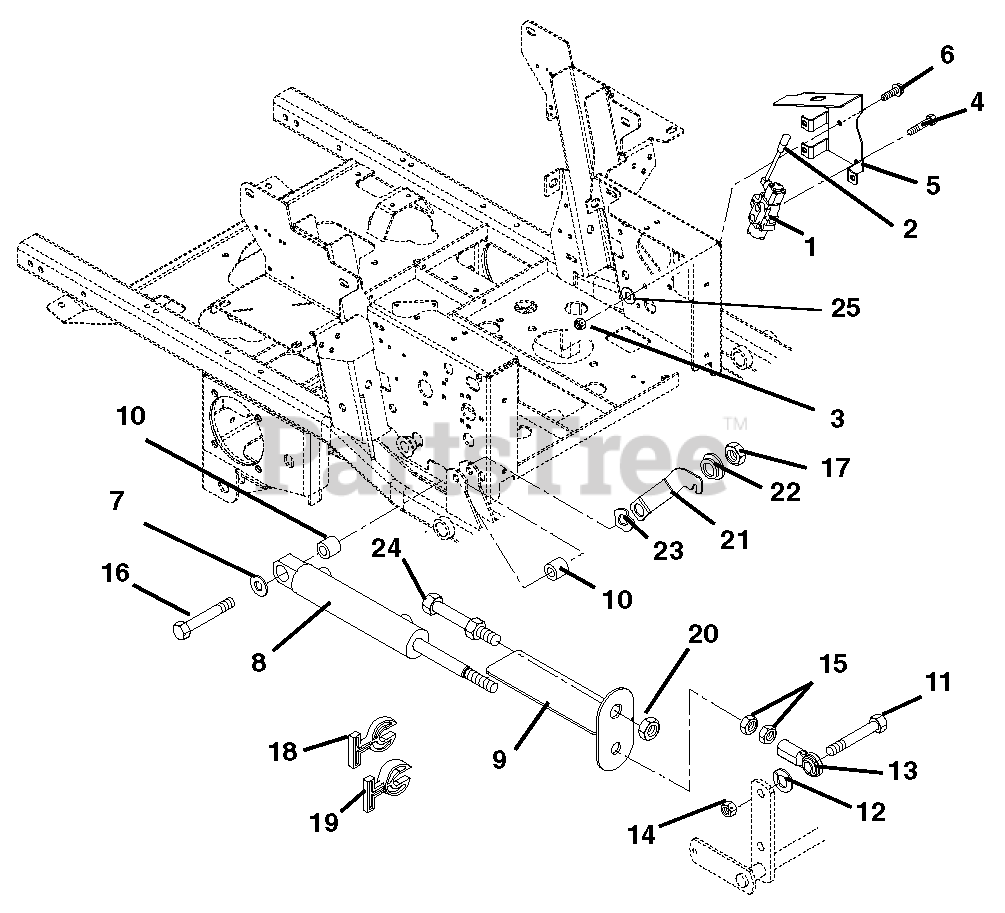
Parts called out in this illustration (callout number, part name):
1	Valve, Hydraulic
2	Knob (Service Only)
3	Nut, Locking Center .31-18
4	Bolt, Hex .31-18 x 2.0 Grade 5
5	Bracket, Valve Mounting
6	Screw, Tapping .38-16 x .50 Hex Washer Head
7	Washer, Flat Steel .515 x 1.625 x .25
8	Cylinder, Hydraulic Lift
9	Strap, Cut Indicator / Guard
10	Bushing .516 x 1.00 x 1.05
11	Bolt, Hex .62-11 x 2.25 Grade 8
12	Washer, Lock .62 x .156
13	Rod End, Right Hand Female .625
14	Nut, Locking Center .62-11
15	Nut, Jam .625-18
16	Bolt, Hex .50-13 x 3.75 Grade 5
17	Nut, Locking Top Flange .50-13
18	Stop, Cylinder .34 Thick
19	Stop, Cylinder .68 Thick
20	Nut, Jam .75-16
21	Latch, Footboard
22	Bushing, Flange .515 x .75 x .275 x 1.12
23	Washer, Wave .076 x 1.12 x .08
25	Washer, Locking .31 x .078 Regular
